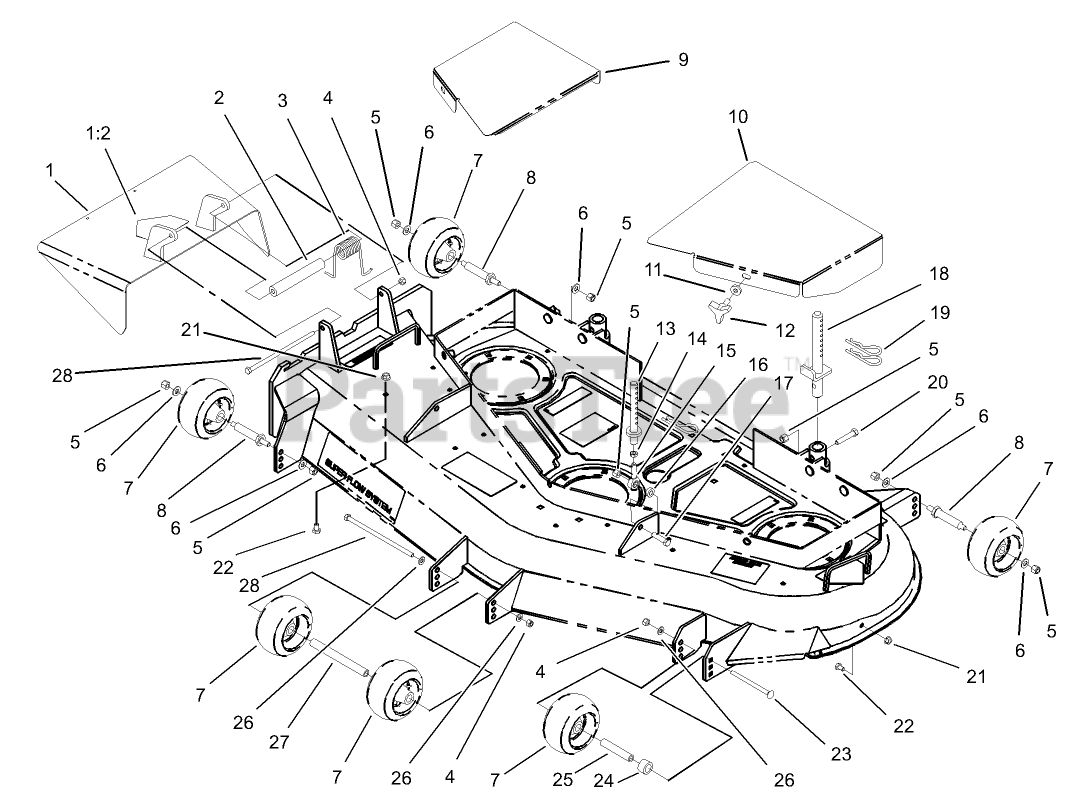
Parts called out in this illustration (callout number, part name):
1	Deflector ASM
1:2	DECAL-DANGER
2	SPACER
3	SPRING-TORSION
4	NUT-LOCK, NI
5	NUT-LOCK, NI
6	WASHER-FLAT
7	WHEEL-GAGE
8	SPACER
9	COVER-BELT, RH
10	COVER-BELT, LH
11	WASHER-RUBBER
13	FRONT PIN ASM
14	NUT-HJ
15	BALLJOINT
16	SPACER
17	SCREW-HH
18	REAR PIN ASM
19	PIN-HAIR
20	SCREW-HH
21	NUT-HF
22	SCREW-HH
23	SCREW-CARR
24	SPACER-WHEEL
25	BUSHING-ROLLER
26	WASHER-PLAIN
27	SPACER-WHEEL
28	SCREW-HH
